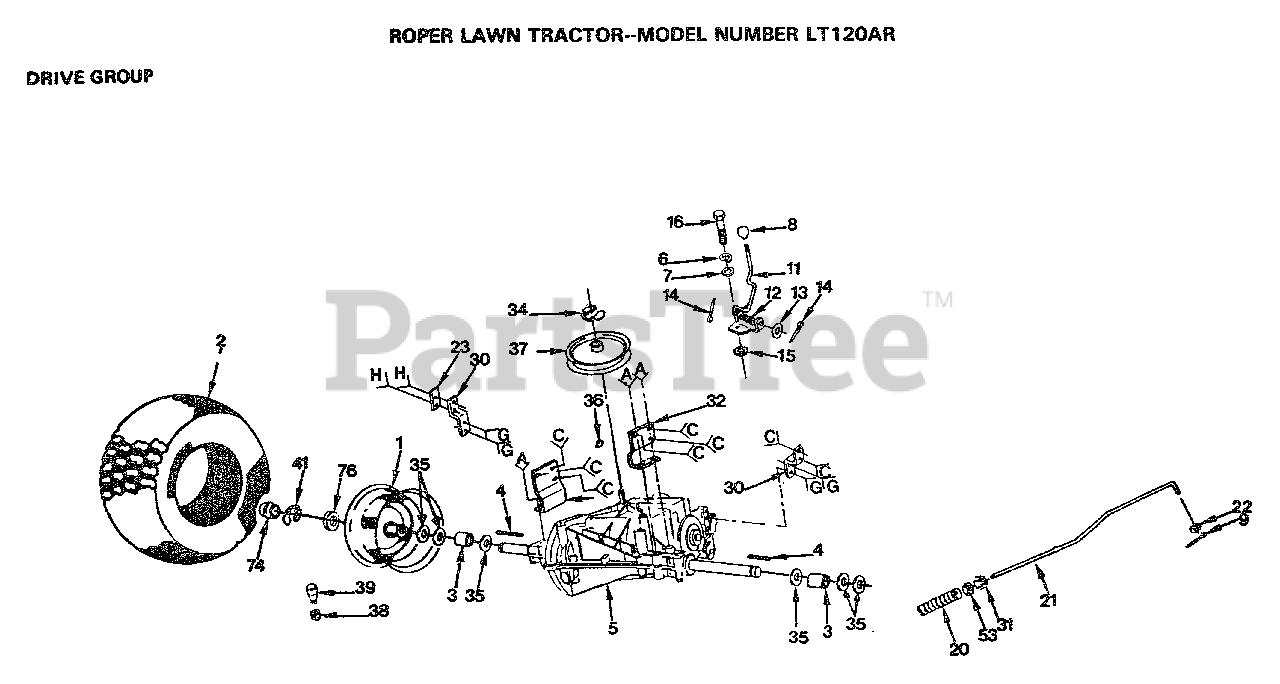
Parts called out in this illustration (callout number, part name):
3	SPACER LT
6	LOCKWASHER
7	WASHER LT
8	KNOB T (1/2-HOLE)
9	COTTER PIN
10	PLATE SHIFT LT
12	SPRING LT
13	WASHER
14	PIN COTTER 1/8
15	WASH-SHFT PLT LT
20	SPRING ROD LT
22	WASHER
23	PLATE-STRAP LT
30	"STRAP, TORQUE LT"
31	NUT
32	BRACKET LT
38	VALVE CAP
39	VALVE STEM LT
41	E-RING LT
74	HUB CAP
75	LOCKNUT
